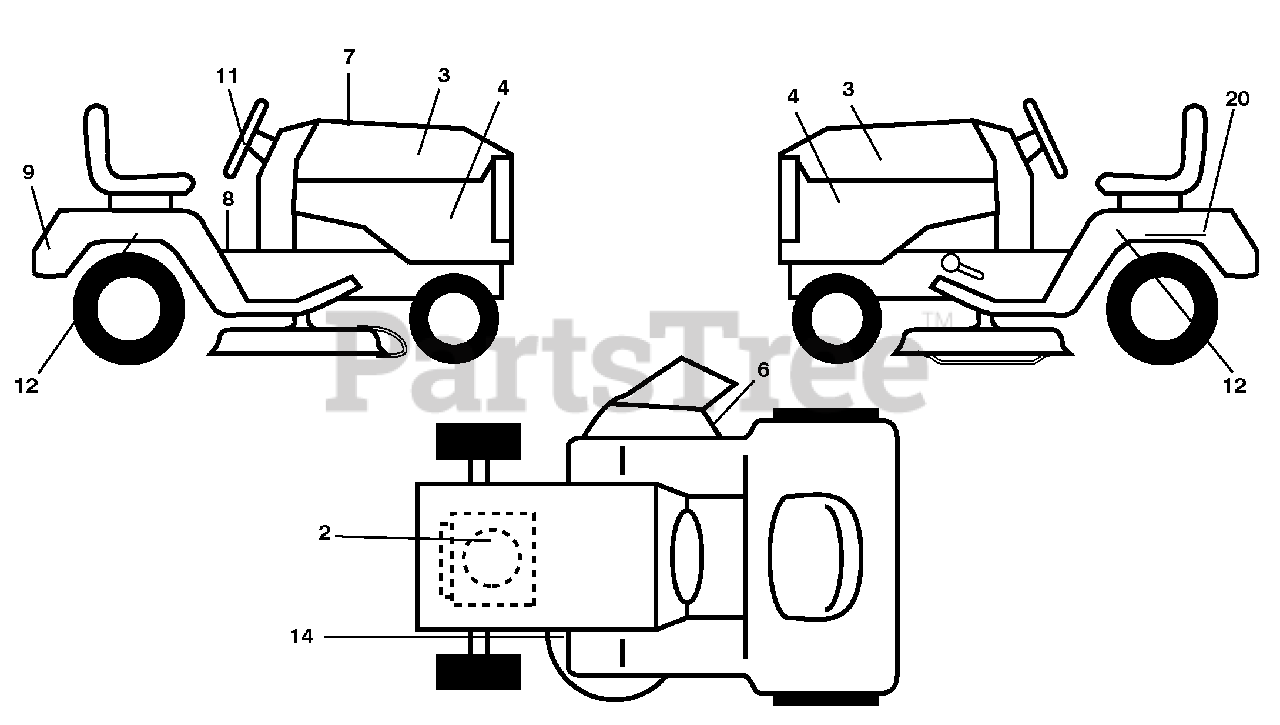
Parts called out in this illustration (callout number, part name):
2	Decal Eng. H.P.
4	Decal Side Panel Logo
6	Decal Warning, Keep Hand Away
7	Decal Replacement Parts
8	Decal Fender Warn S/F
9	Decal Fender Logo
11	Decal Ins Strg Whl
12	Decal Fend SD
14	Decal V-Belt Schematic
20	Decal Bat Dan/Psn
20	Decal Bypass
20	Pad Footrest LH
20	Pad Footrest RH
20	Manual Operator's (English/French)
20	Manual Operator's (Spanish)
20	Manual Parts (English/French)
